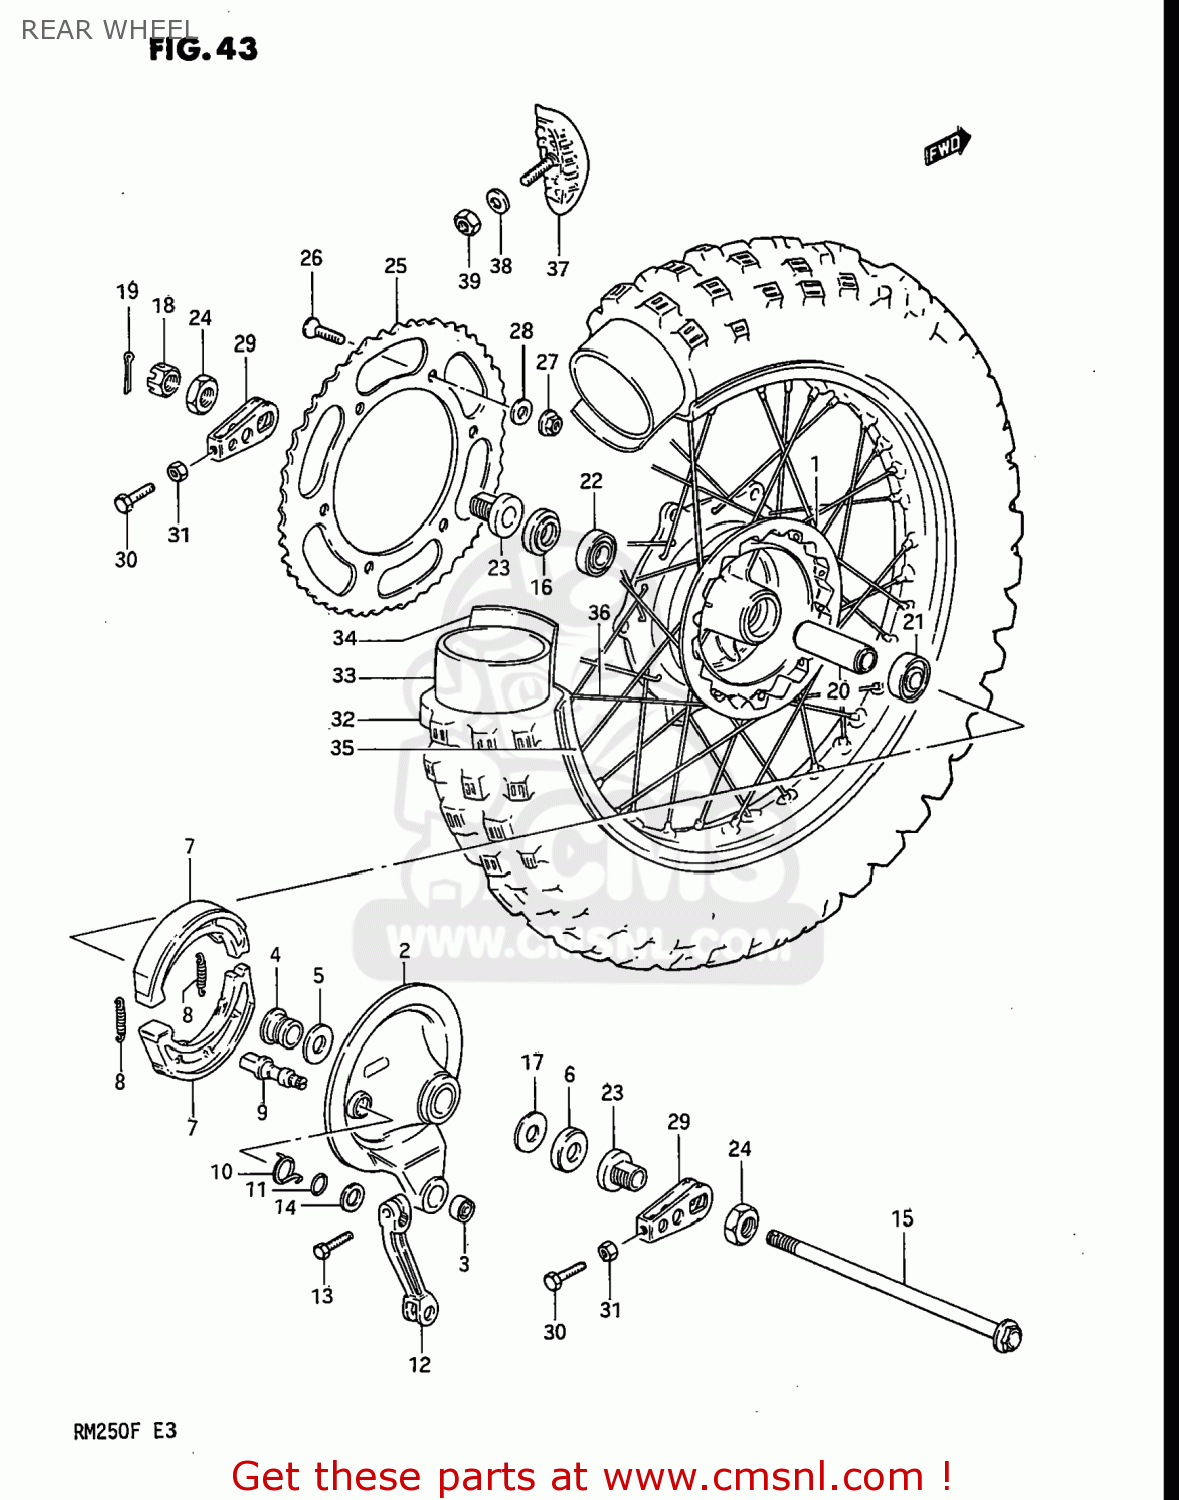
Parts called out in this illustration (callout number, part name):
1	DRUM,REAR HUB
2	PANEL SET
3	BEARING
4	SPACER,REAR HUB PANEL
5	SEAL,OIL(24X31X5)
6	CVR,RR BRAKE AHR PNL DUST SEAL
7	SHOE,BRAKE
8	SPRING,BRAKE SHOE
9	CAM,FR BRAKE
10	SPRING
11	O RING(D:2.5,ID:11.4)
12	LEVER,REAR BRAKE CAM
13	BOLT
14	WASHER(12.5X20X1)
15	AXLE,REAR
16	SPACER,REAR AXLE,LEFT
17	WASHER
18	NUT
19	PIN,COTTER
20	SPACER,REAR HUB BEARING
21	BEARING
22	BEARING
23	SPACER,CHAIN ADJUSTER
24	NUT
25	SPROCKET,REAR
26	SCREW(8X40)
27	NUT
28	WASHER
29	ADJUSTER,CHAIN
30	BOLT
31	NUT
32	TIRE
33	TUBE,INNER
34	PROTECTOR,WHEEL,INNER
35	RIM,REAR WHEEL (2.15X18)
36	SPOKE SET,REAR
37	STOPPER,BEAD
38	WASHER
39	NUT
